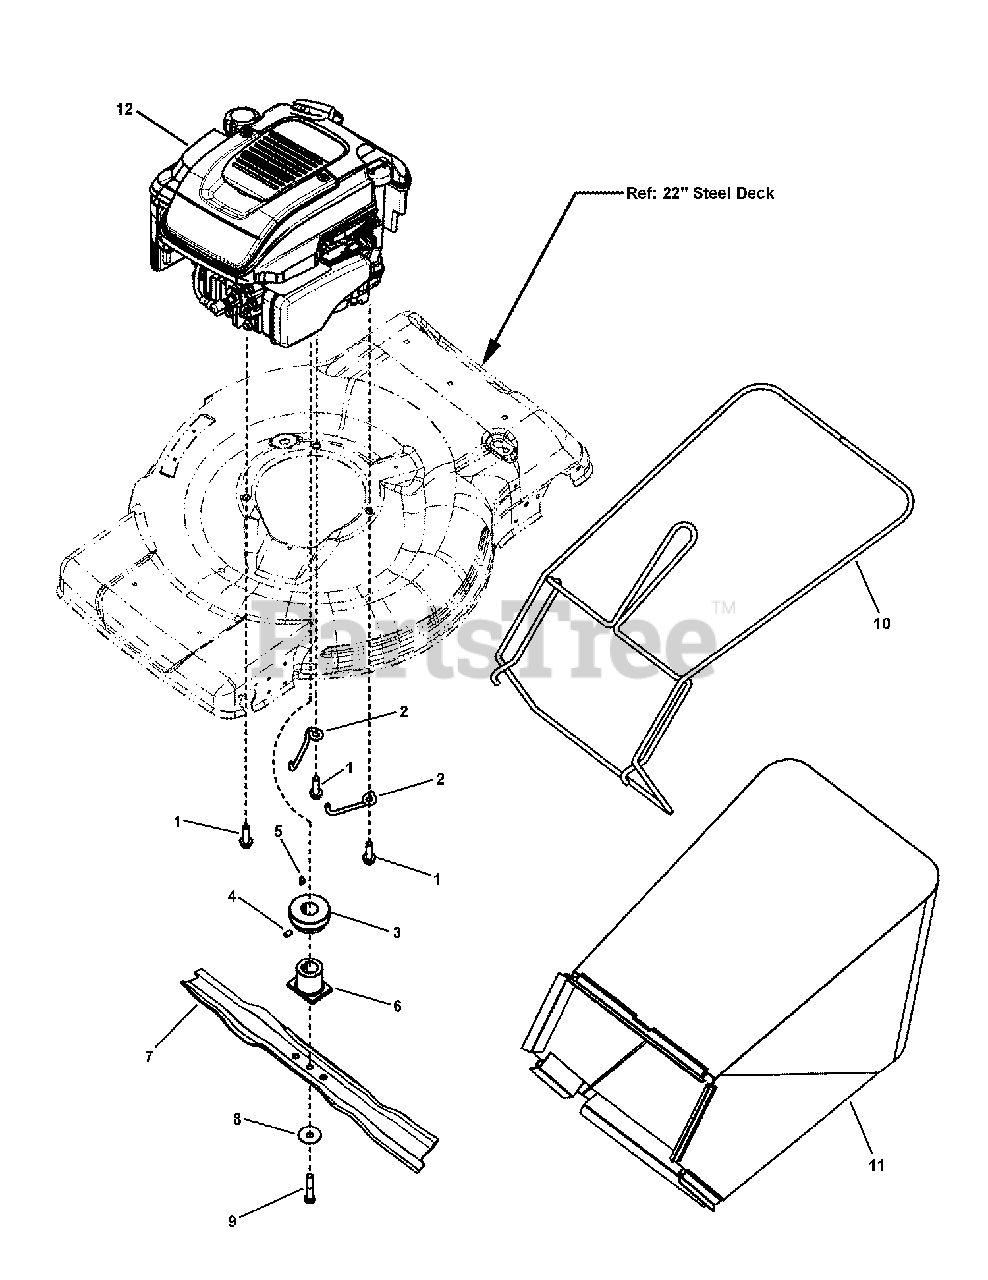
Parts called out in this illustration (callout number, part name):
1	SCREW, 3/8-16 x 1-1/4" Hex Washer Self-Tap
2	BELT GUIDE, Engine
3	PULLEY, Engine
4	SET SCREW, 5/16-18 x 1/2" Hex Recess
5	KEY, #HP-506 Hi-Pro
6	BLADE HUB, 21" WBM, Rear Drive, 2 Position
7	BLADE, Wave, Steel Deck
8	WASHER, Cone
9	SCREW, 3/8-24 x 2" Hex Head Cap, GR 5
10	BAG FRAME, Rear Discharge (weldment)
11	GRASS BAG, 22" Rear Discharge
12	* ENGINE, B&S, 700 Series, X-Spec
12	* ENGINE, B&S, 700 Series, ES, X-Spec
12	* ENGINE, B&S, 700 Series, B3, X-Spec
12	* ENGINE, B&S, 700 Series, Quantum, ES
